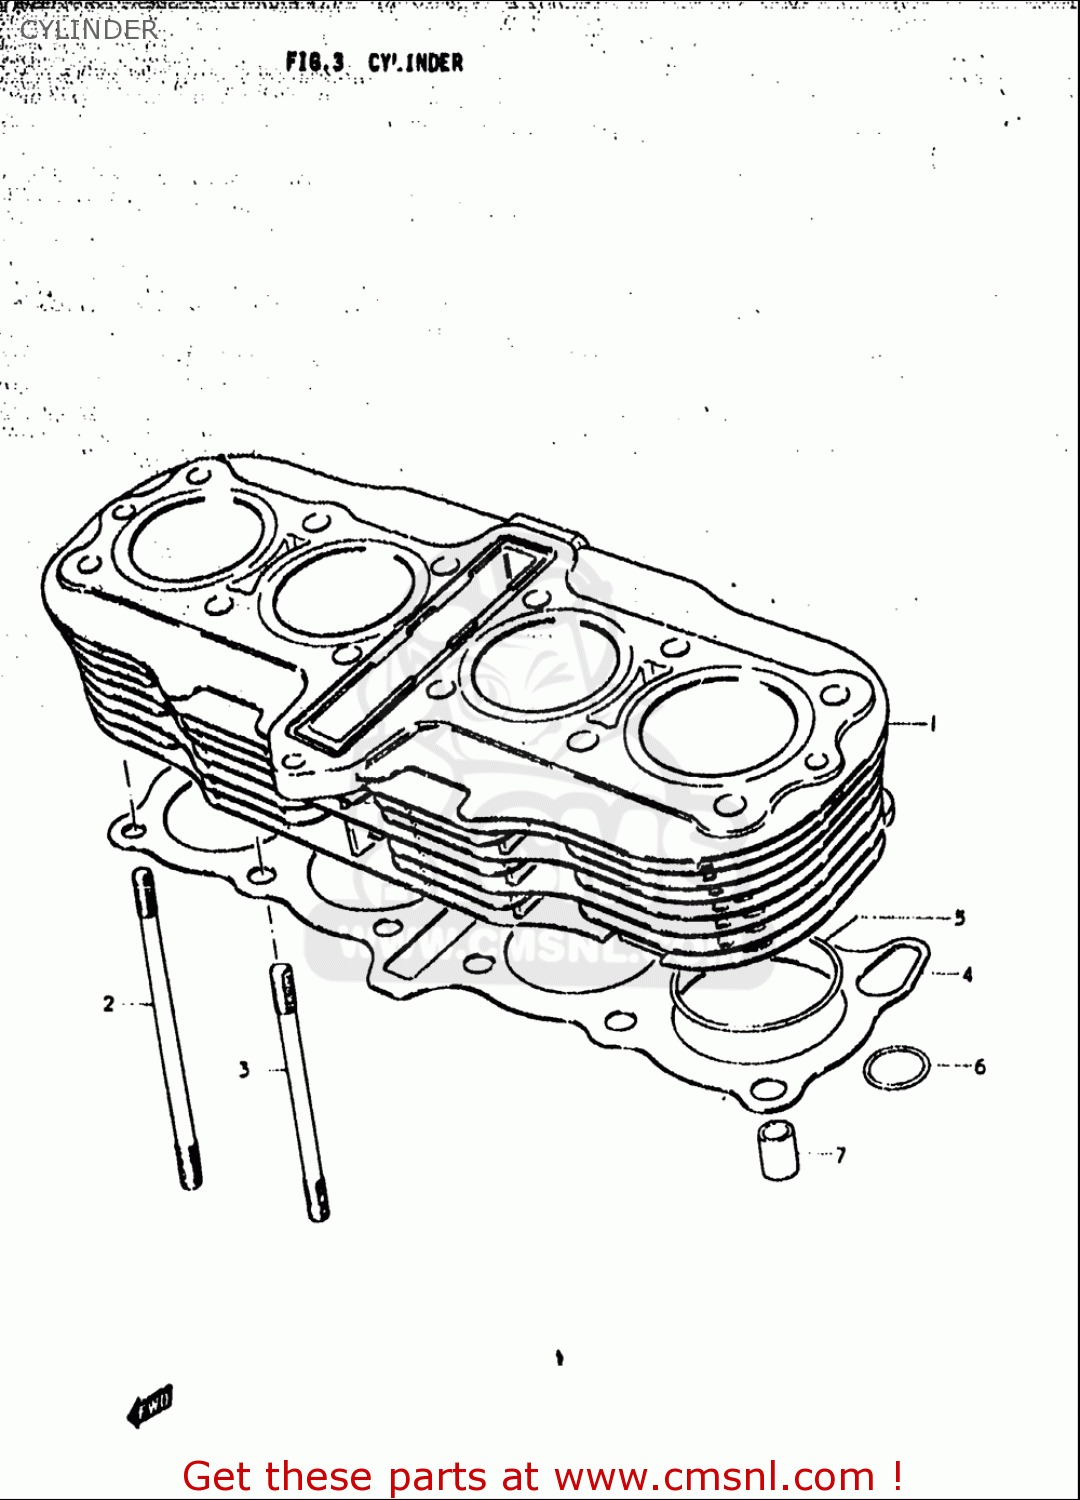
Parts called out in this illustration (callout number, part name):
2	BOLT,STUD
3	BOLT,STUD
4	GASKET,CYLINDER (NAS)
5	O RING(D:2,ID:74)
6	O RING(D:3.05)
7	PIN
